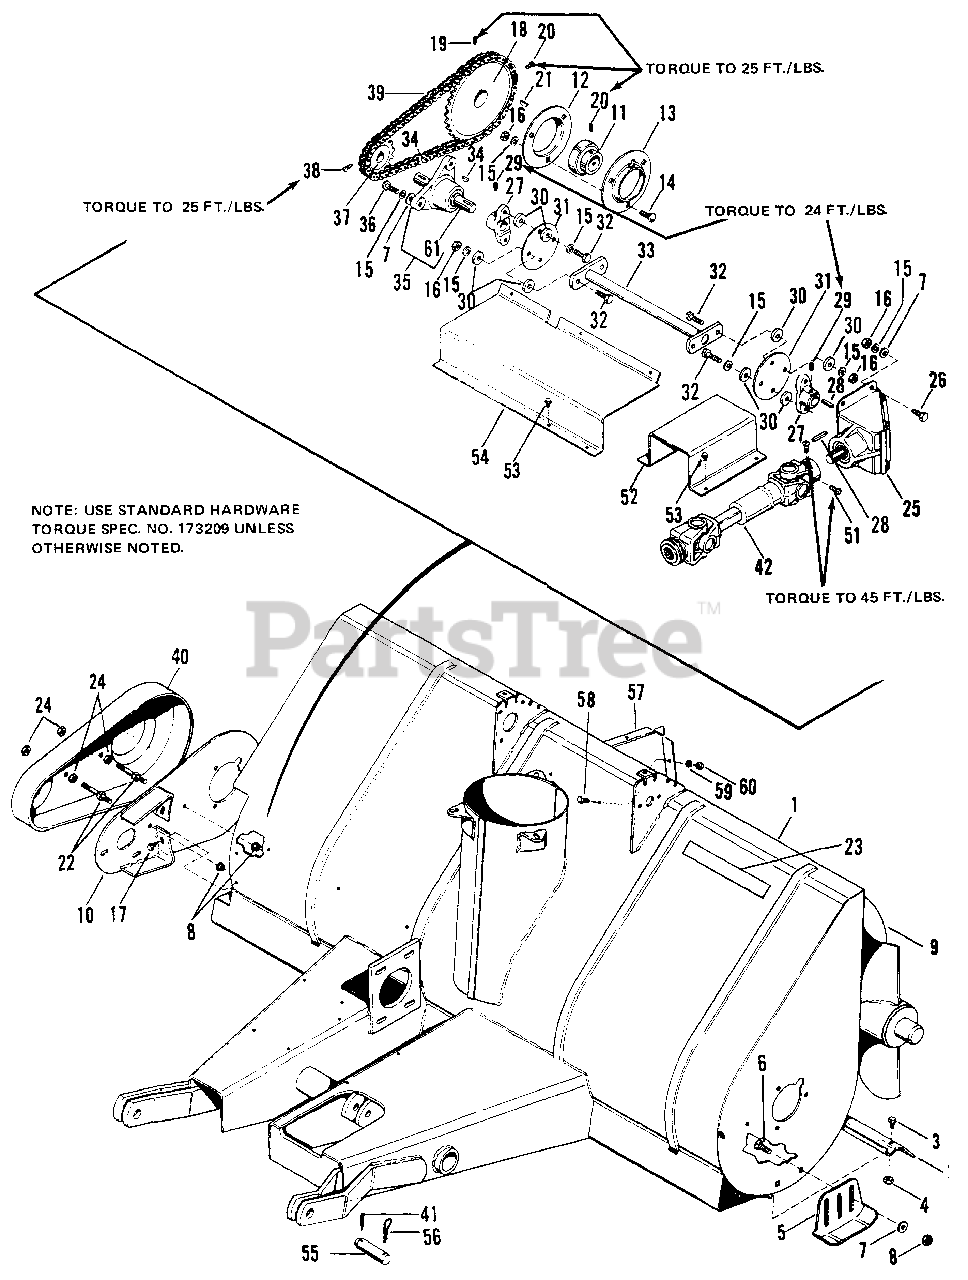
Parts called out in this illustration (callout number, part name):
32	CAPSCREW, Hex Hd., 3/8-16 x 1-1/4
33	SHAFT ASSY, Drive
34	KEY, Hi-Pro, 3/16 x 3/4
35	SHAFT & BEARING ASSY, Flange
36	SCREW, Special
37	SPROCKET, 14 T
38	SCREW, Set, Sq. Hd., Cup Pt., 5/16-18 x 3/8, Gr. 8
39	CHAIN, w/Conn. Link
40	GUARD, Chain
41	PIN, Cotter, 1/8-1-1/2
42	SHAFT ASSY, Drive
51	SCREW, Set. Sq. Hd., Cup Pt., 3/8-24 x 5/8, Gr. 8
53	SCREW, Hex, Wshr. Hd., Taptite, 1/4-20 x 3/8
55	PIN, Hitch
56	CLIP, Spring
57	DEFLECTOR
58	CAPSCREW, Hex Hd., 5/16-18 x 5/8
59	LOCKWASHER, Spring, 5/16
60	NUT, Hex, 5/16-18
61	SHAFT & BEARING
